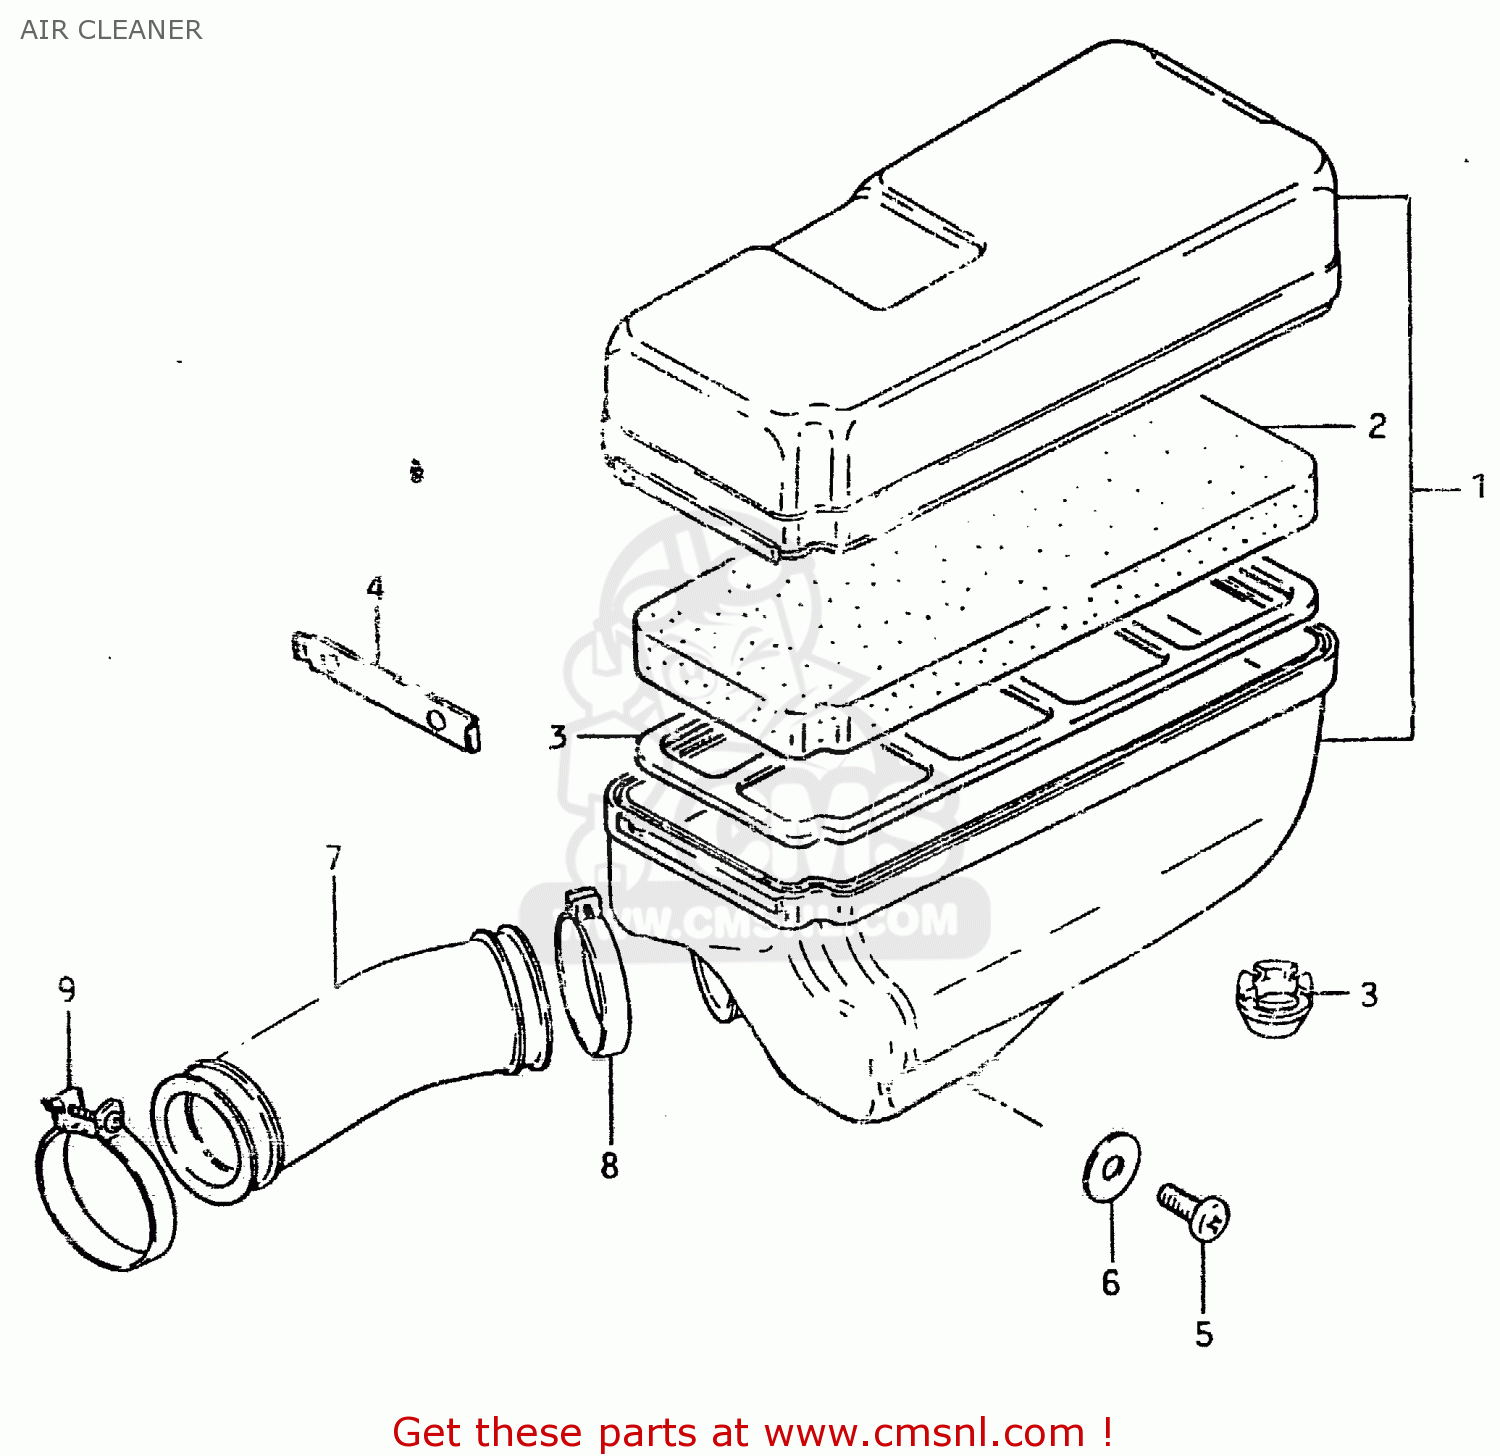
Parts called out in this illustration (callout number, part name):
1	CLEANER ASSY,A
2	FILTER
3	CAP,DRAIN
4	SLIDER
5	SCREW
6	WASHER
7	TUBE,AIR CLEANER OUTLET
8	CLAMP
9	CLAMP
